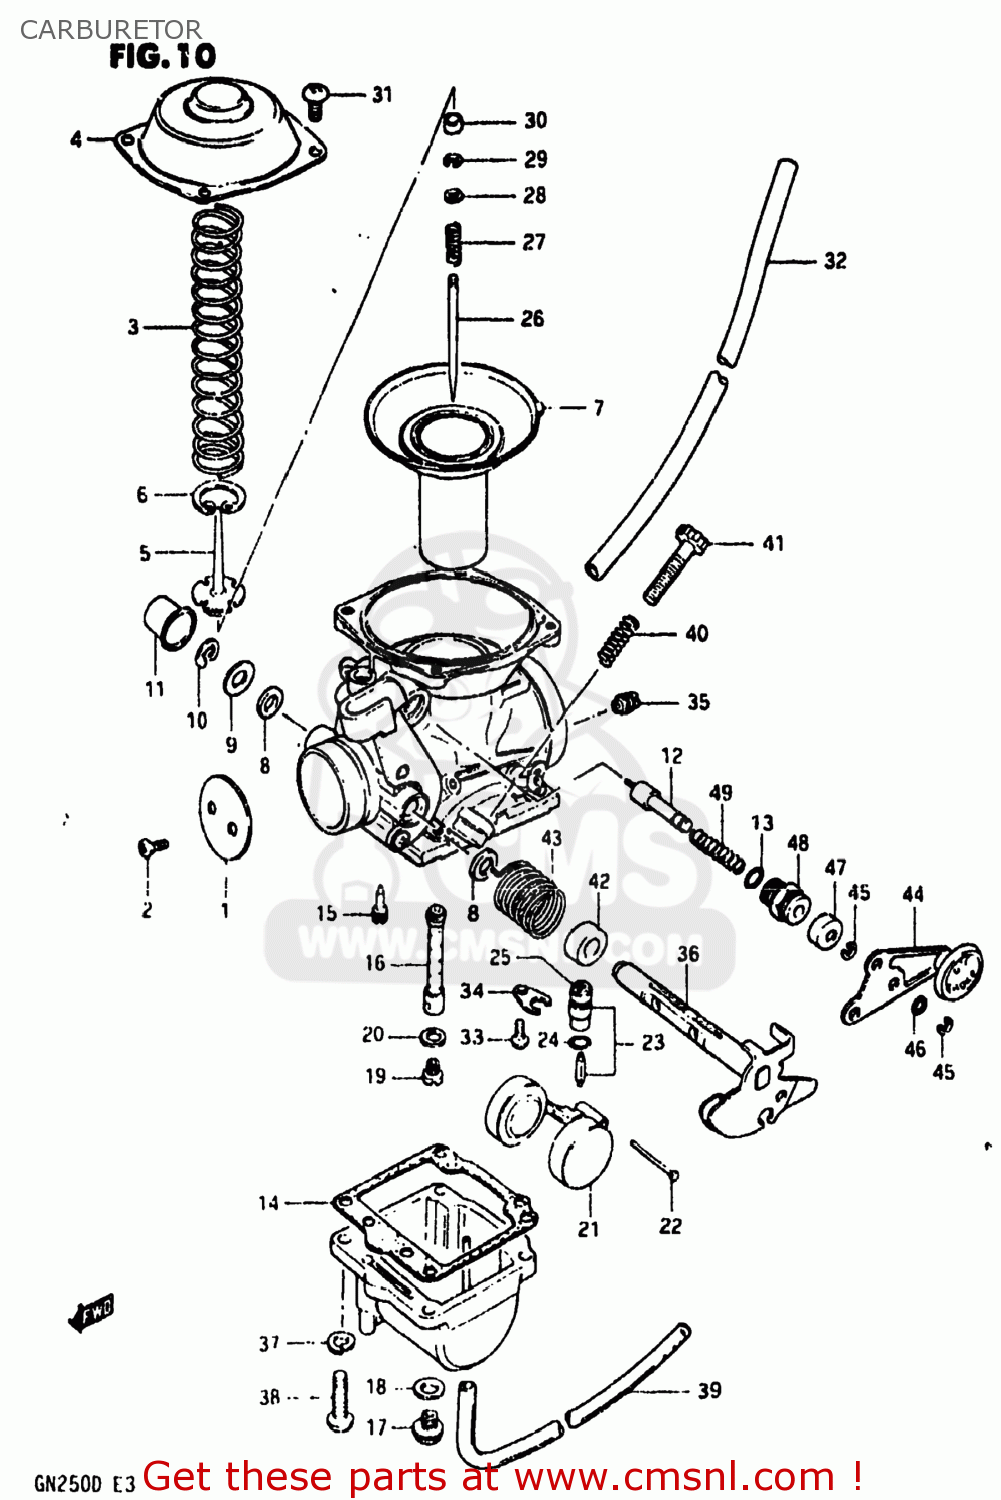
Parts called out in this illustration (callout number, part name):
1	VALVE,THROTTLE
2	SCREW
3	SPRING
4	COVER
5	HOLDER,GUIDE
6	E RING
7	DIAPHRAGM ASSEMBLY
8	SEAL
9	GASKET,THROTTLE SHAFT (NAS)
10	E RING
11	CAP
12	PLUNGER ASSY
13	O RING
14	GASKET,FLOAT CHAMBER (NAS)
15	JET,PILOT(42.5)
16	JET,NEEDLE
17	PLUG,DRAIN
18	GASKET (NAS)
19	JET,MAIN(130)
20	WASHER
21	FLOAT
22	PIN,FLOAT
23	VALVE ASSEMBLY,NEEDLE
24	O RING
25	FILTER
26	NEEDLE JET
27	SPRING
28	WASHER
29	CLIP
30	RING
31	SCREW
32	HOSE
33	SCREW 4X6
34	PLATE
35	JET,AIR(150)
36	SHAFT ASSEMBLY,THROTTLE
37	LOCK WASHER
38	SCREW
39	HOSE
40	SPRING,THROTTLE ADJUST
41	SCREW,THROTTLE STOP
42	RING
43	SPRING,THROTTLE SHAFT
44	STARTER LEVER ASSY
45	E RING
46	WASHER
47	CAP,STARTER VALVE
48	GUIDE SCREW,PLUNGER
49	SPRING
